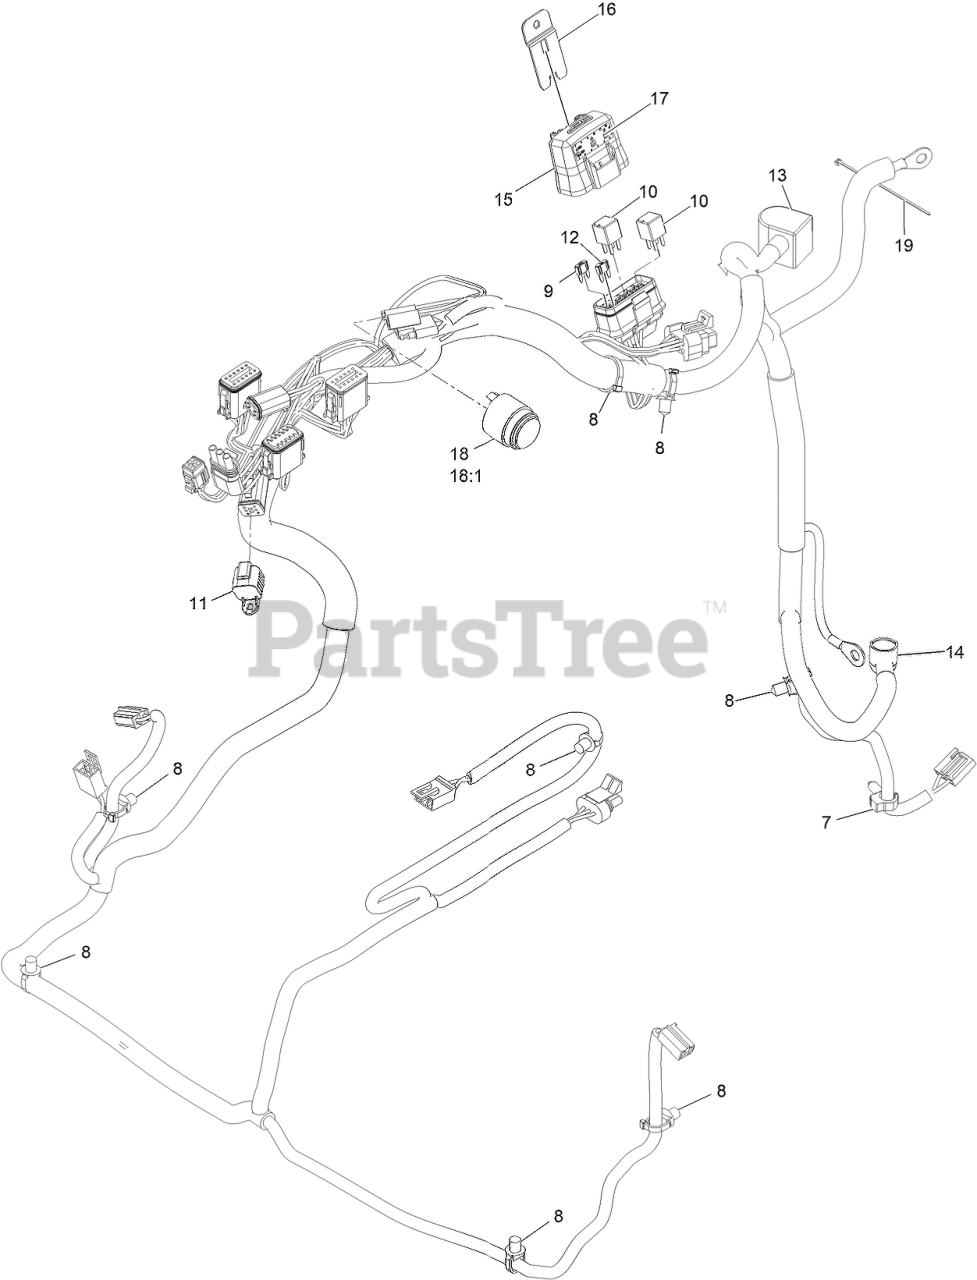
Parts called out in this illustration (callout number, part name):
7	CLIP-HARNESS
8	CLIP-TIE
9	FUSE-MINI BLADE, 20 AMP
10	RELAY-MICRO
11	CAP-PLUG, 6 WAY
12	FUSE-MINI BLADE, 15 AMP
13	INSULATOR-BATTERY
14	INSULATOR-SOLENOID
15	COVER-BLOCK, FUSE
16	CLIP-MOUNTING
17	Decal-Fuse
18	Audio Alarm ASM
18:1	Nut-Plastic, Knurled
19	TIE-CABLE
